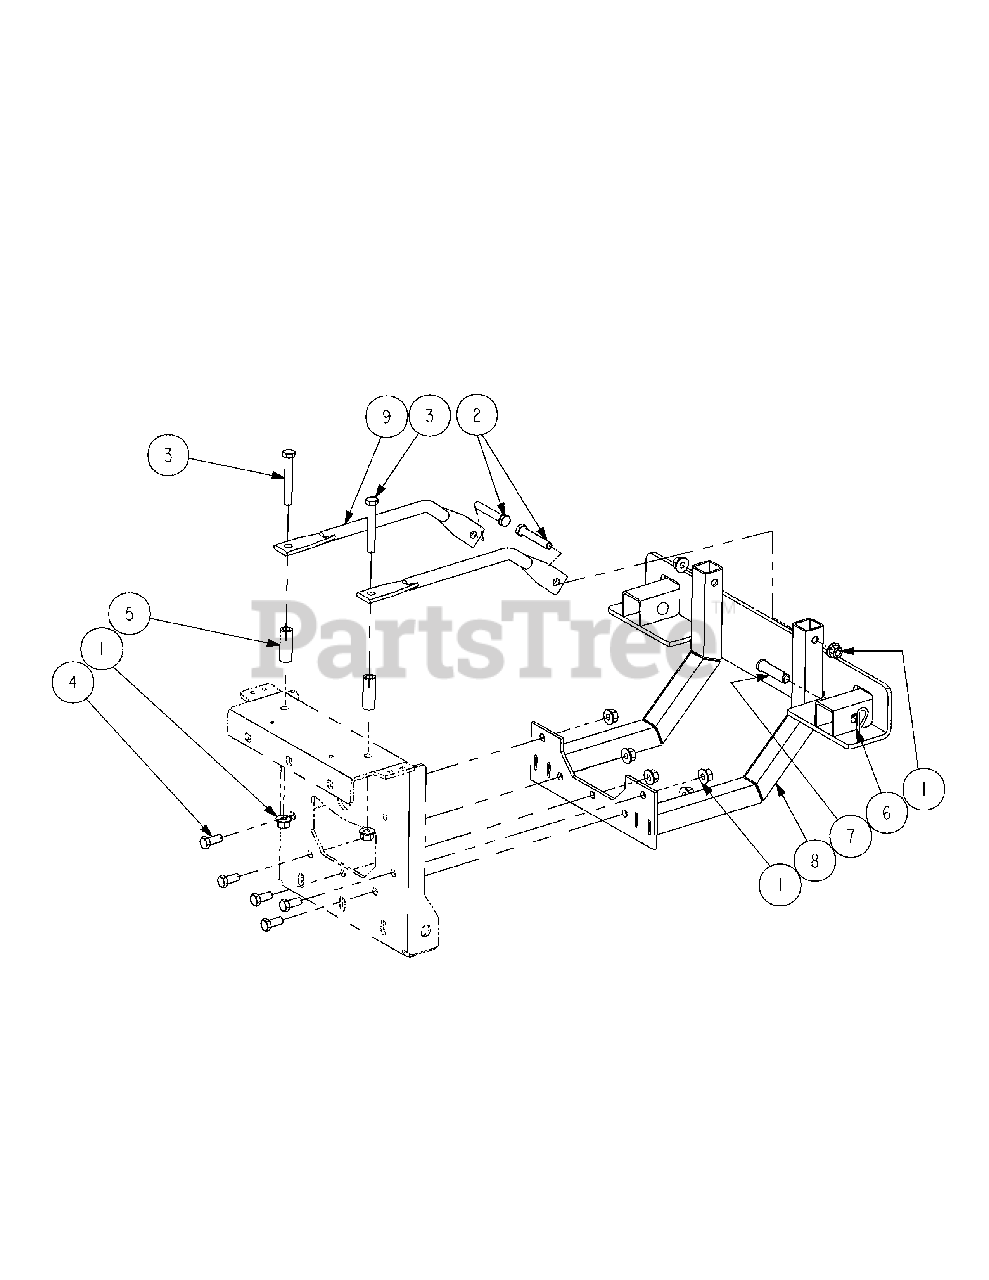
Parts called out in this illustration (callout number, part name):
1	Nut, 3/8-16, Flange Lock
2	HHCS, 3/8-16 x 2.25
3	HHCS, 3/8-16 x 2.75
4	HHCS, 3/8-16 x .875
5	Spacer, .39 ID x .63 OD x 1.75
6	Hair Pin, 1/8
7	Clevis Pin, 1/2 x 2.00 Long
8	Front Mount Spreader Support
9	Front Spreader Link Rod
